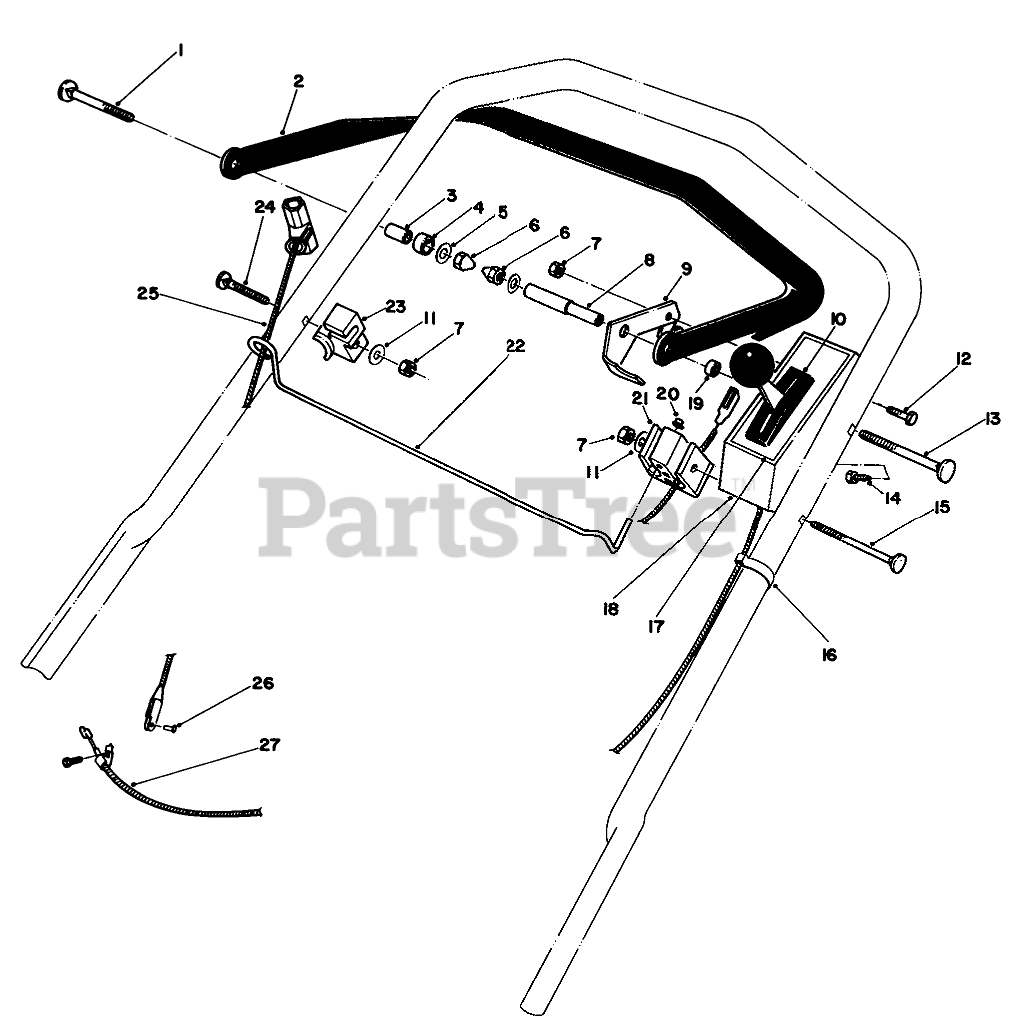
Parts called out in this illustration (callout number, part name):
1	5/16-18 X 2 HNDLE SCREW
2	Bar-Control
3	Spacer
4	SPACER-NYLON
5	WASHER-PLAIN
6	NUT-LOCK, CAP
7	NUT-LOCK, NI
8	Spacer
9	Lever-Control
10	SERVICE THROTTLE CONTRO
11	WASHER-FLAT
12	SCREW-HH
13	5/16-18X3.75 HDLE SCREW
14	SCREW-HWHTF
15	SCREW-HANDLE
16	BOWDEN CLIP
17	Decal-Control Cover
18	Panel-Control (Incl. Ref. #17)
19	Nylon Spacer
20	NUT-SPEED
21	SUPPORT-CABLE
22	ROPE ROD PLATED
23	ROD CATCH
24	SCREW-HANDLE
25	Rope-Starter
27	BRAKE CABLE
